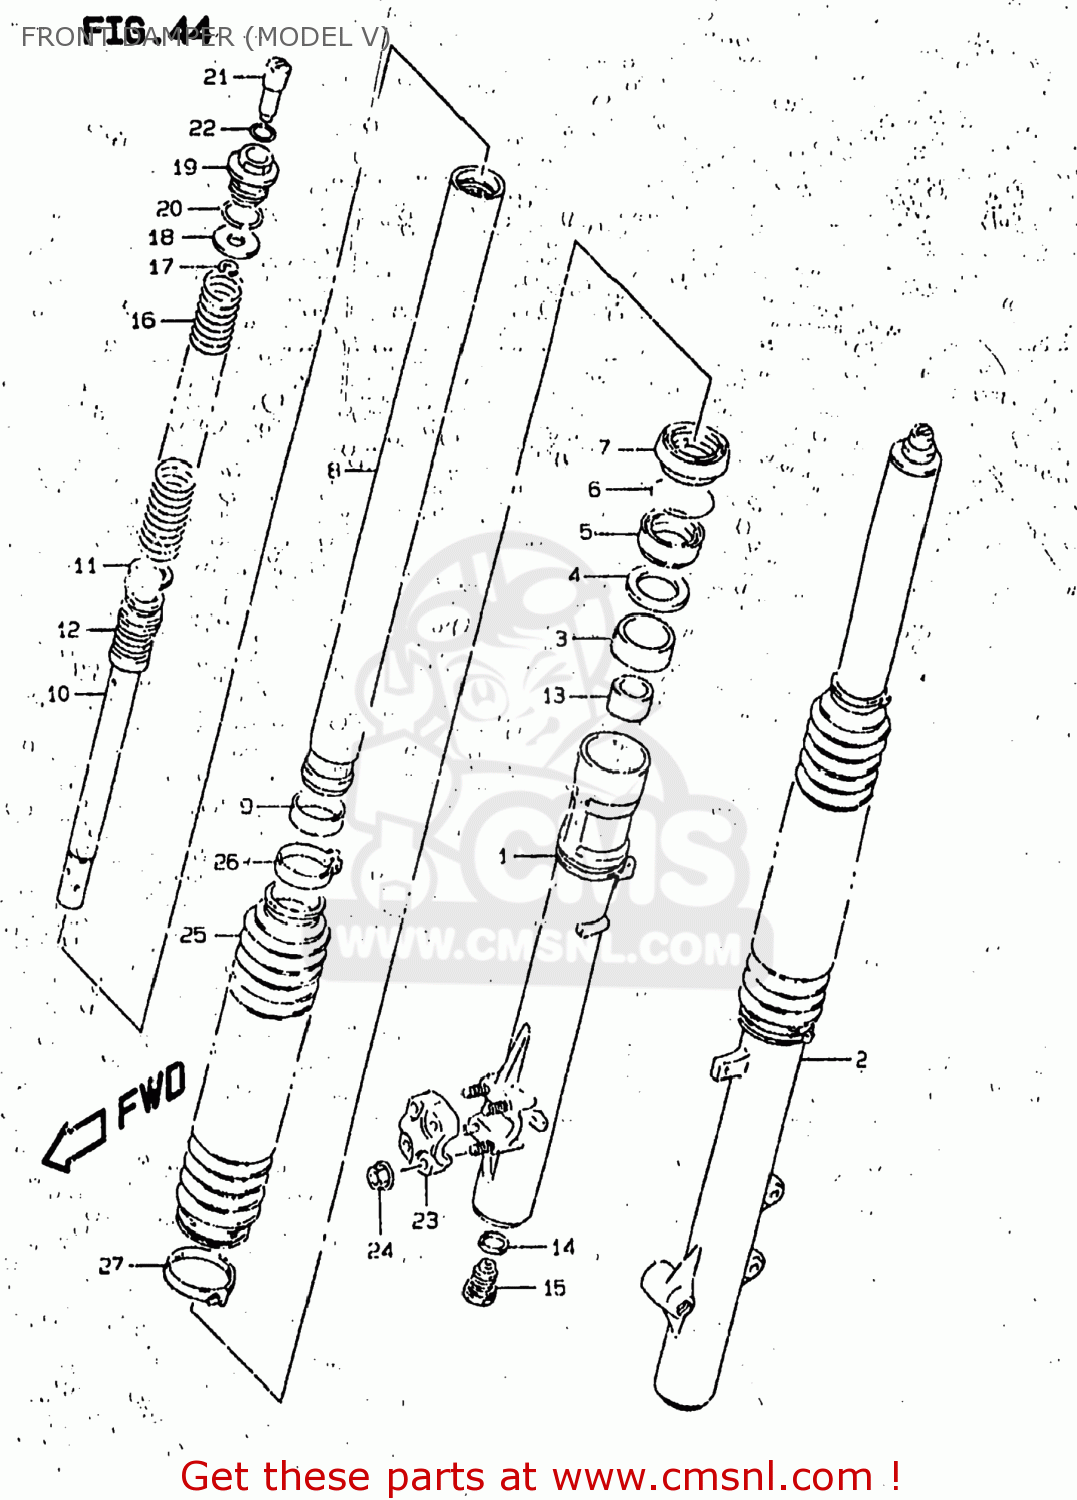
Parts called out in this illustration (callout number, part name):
0	DAMPER ASSEMBLY,FRONT FORK
1	TUBE,OUTER,RIGHT
2	TUBE,OUTER,LEFT
3	BUSH,GUIDE
4	SPACER,SEAL
5	SEAL,OIL
6	CIRCLIP,FORK OIL SEAL
7	DUST SEAL
8	TUBE,INNER
9	BUSH,SLIDE
10	CYLINDER
11	RING,PISTON
12	SPRING,REBOUND
13	PIECE,OIL LOCK
14	GASKET (NAS)
15	BOLT,PIECE
16	SPRING,MAIN
17	E RING
18	SEAT,SPRING
19	BOLT,FORK
20	O RING
21	ADJUSTER,SPRING
22	O RING
23	HOLDER,AXLE
24	NUT,HOLDER
25	BOOT
26	BAND,BOOT UPR
27	BAND,BOOT LWR
